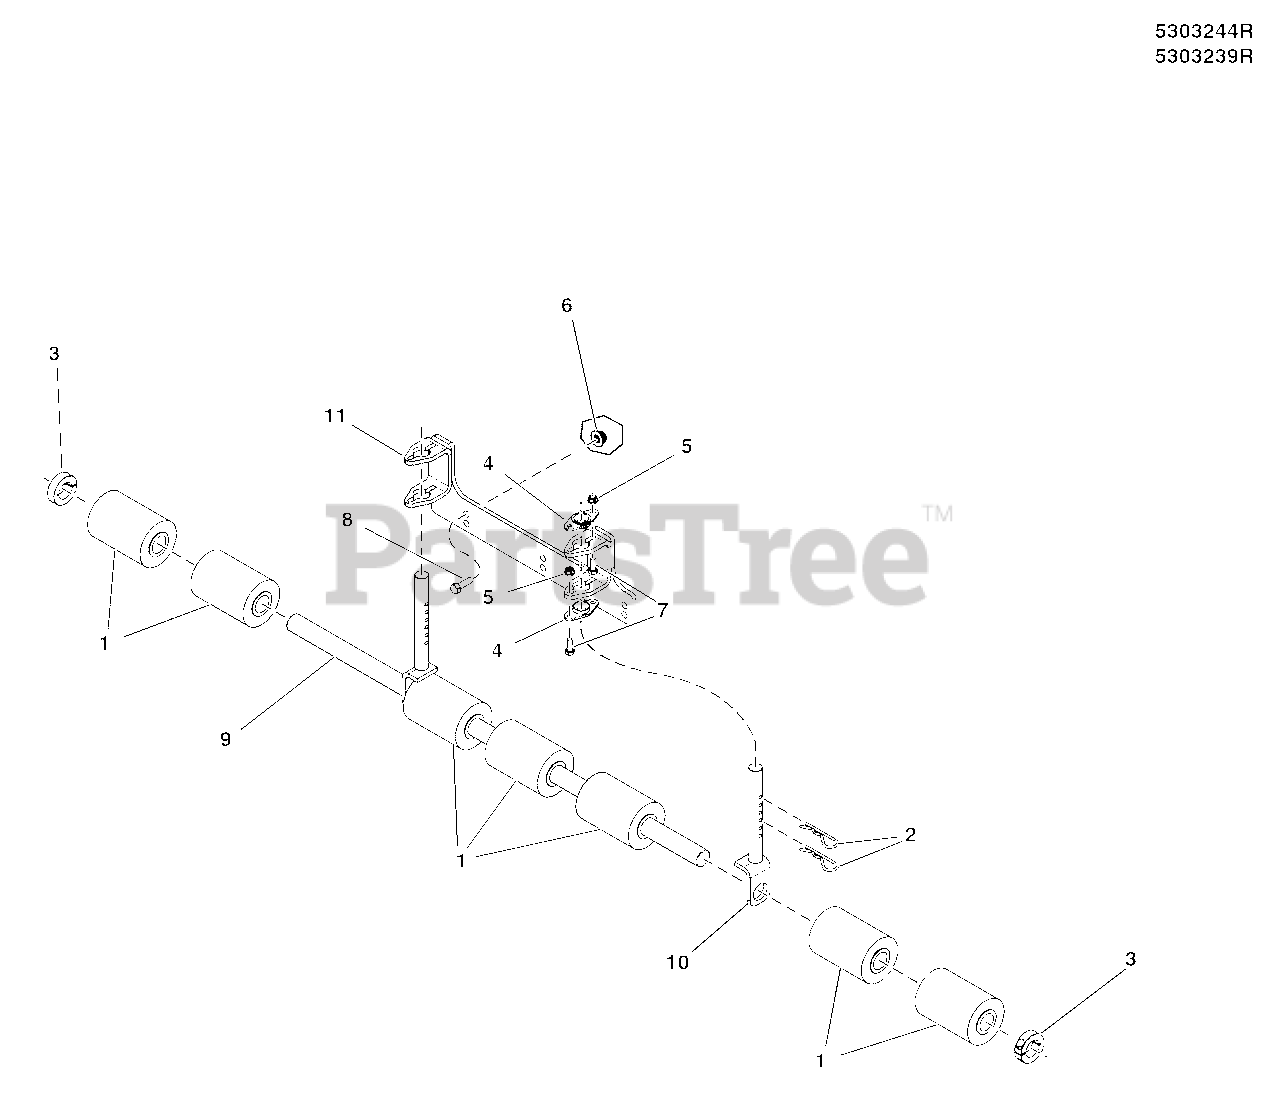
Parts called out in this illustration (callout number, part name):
1	ROLLER W/BUSHINGS BLACK POLY
2	CLIP-HAIR PIN .125DIA SPRG WI 2.56 LG - BLK
3	COLLAR, 1 SPLIT
4	BUSHING, FLANGE, GFL - 20
5	NUT, 5/16-18 HEX SERRATED FLANGE (SMALL)
6	NUT, 1/4-20 HEX NYLOCK FLANGE (5025391)
7	BOLT, 1/4-20 X 3/4 GD5 YZ
8	BOLT, 5/16-18 X 1 GD5 YZ
9	WELD, ROLLER SHAFT, 52 & 61, IS700 - BLK
10	WELD, ROLLER SUPPORT, 52-61, IS700 - BLK
11	WELD, ROLLER SUPPORT, 52" - BLACK
11	WELD, ROLLER SUPPORT, 61" - BLACK
